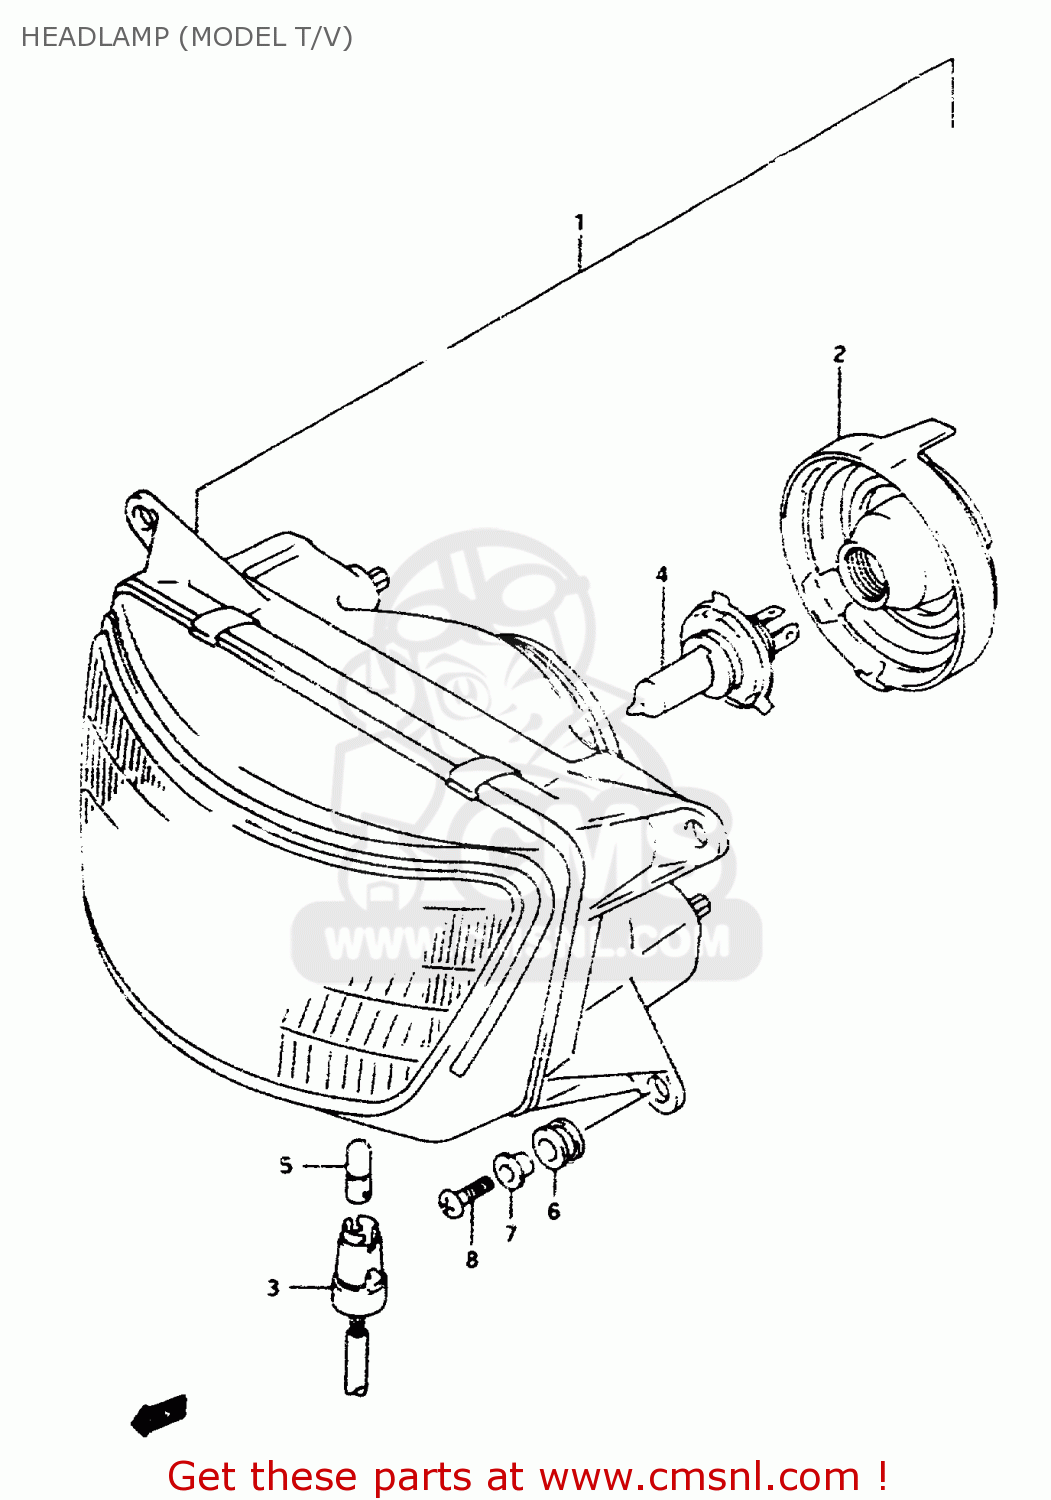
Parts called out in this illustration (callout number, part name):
1	HEADLAMP ASSY
2	COVER,SOCKET
3	CORD ASSY
4	BULB(12V60/55W,H4)
5	BULB(12V4W)
6	CUSHION
7	WASHER
8	SCREW
9	REFLECTOR,REFLEX FR
10	BRACKET
11	NUT
